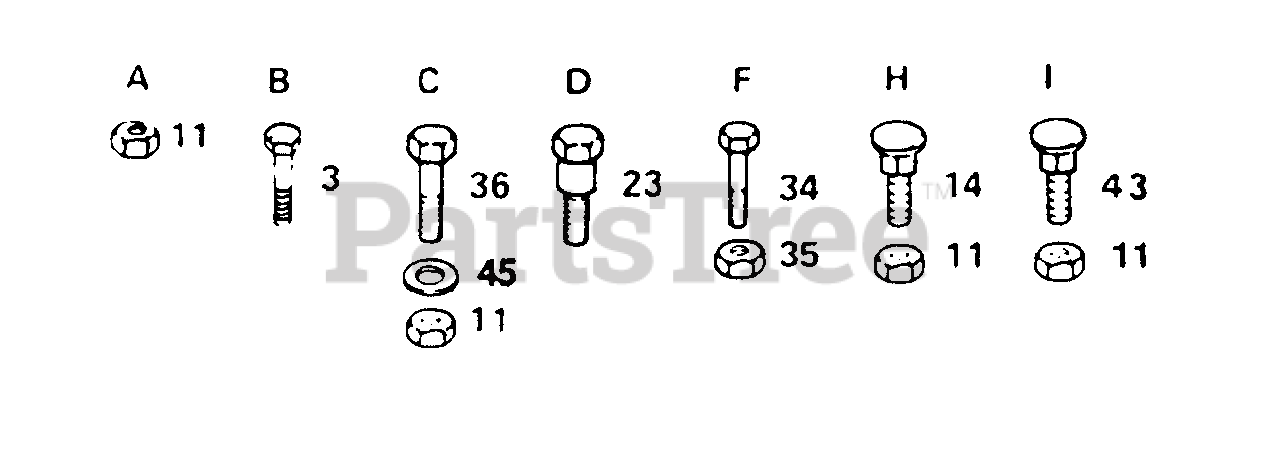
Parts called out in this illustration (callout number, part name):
3	Screw, Tap. Hex Hd. 10-24 x 1/2
11	Nut, Crownlock 3/8-16
14	Bolt, Carriage 3/8-16 x 3/4
23	Bolt, Shoulder 3/8 -16
34	Bolt, Hex 5/16-18 x 3/4
35	Nut, Lock 5/16-18
36	Bolt, Hex 3/8 -16 x 1
43	Bolt, Carriage - 5/16-18 x 3/4
45	Washer, 13/32 X 13/16 X 12 Ga.
